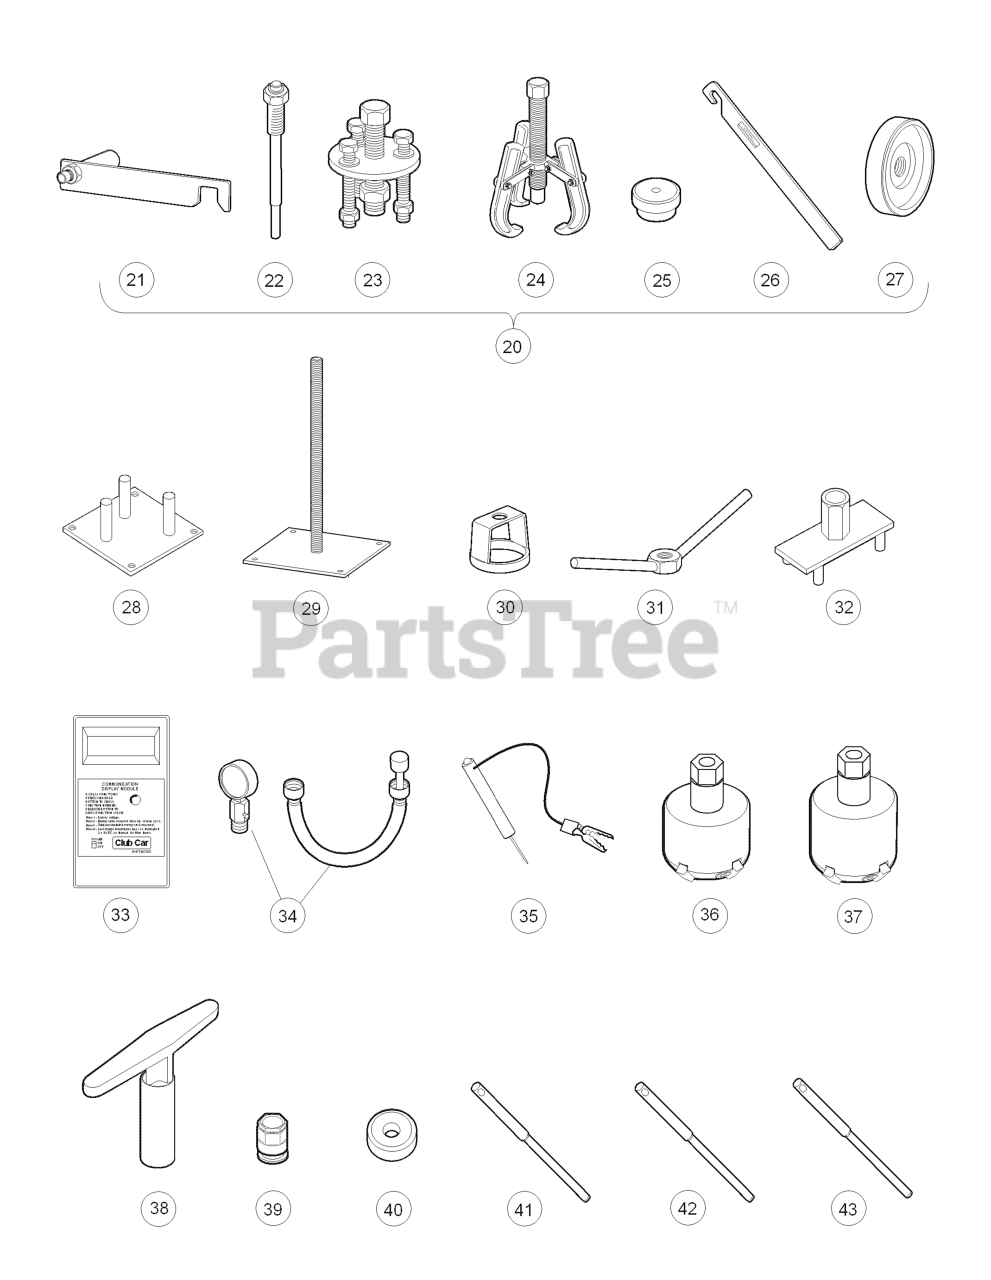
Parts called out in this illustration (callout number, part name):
20	C.C. CLUTCH TOOL KIT
21	TOOL, CLUTCH ALIGNMENT
22	TOOL, CLUTCH PULLER
23	CLUTCH DRIVE HUB PULLER
24	DRIVEN CLUTCH CAM PULLER
25	DRIVEN CLUTCH PULLER PLUG
26	DRIVE CLUTCH HOLDER TOOL ASM.
27	PRESS WELDMENT
28	TOOL-STATIONARY PRIMARY
29	TOOL-SPRING COMPRESSION BASE
30	TOOL-SPRING COMPRESSION COLAR
31	TOOL-SPRING COMPRESSION COLAR
32	TOOL-SPIDER PRIMARY
33	COMMUNICATION DISPLAY MODULE
34	COMPRESSION GUAGE AND ADAPTER
35	CONTINUITY TESTER
36	CUTTER, VALVE SEAT, #122
37	CUTTER, VALVE SEAT, #115
38	ADAPTER, T-WRENCH
39	ADAPTER, T-WRENCH
40	Cutter, Valve Seat, 60 Degree
41	PILOT, 6.6 MM
42	PILOT, 6.62 MM
43	PILOT, 6.65 MM
